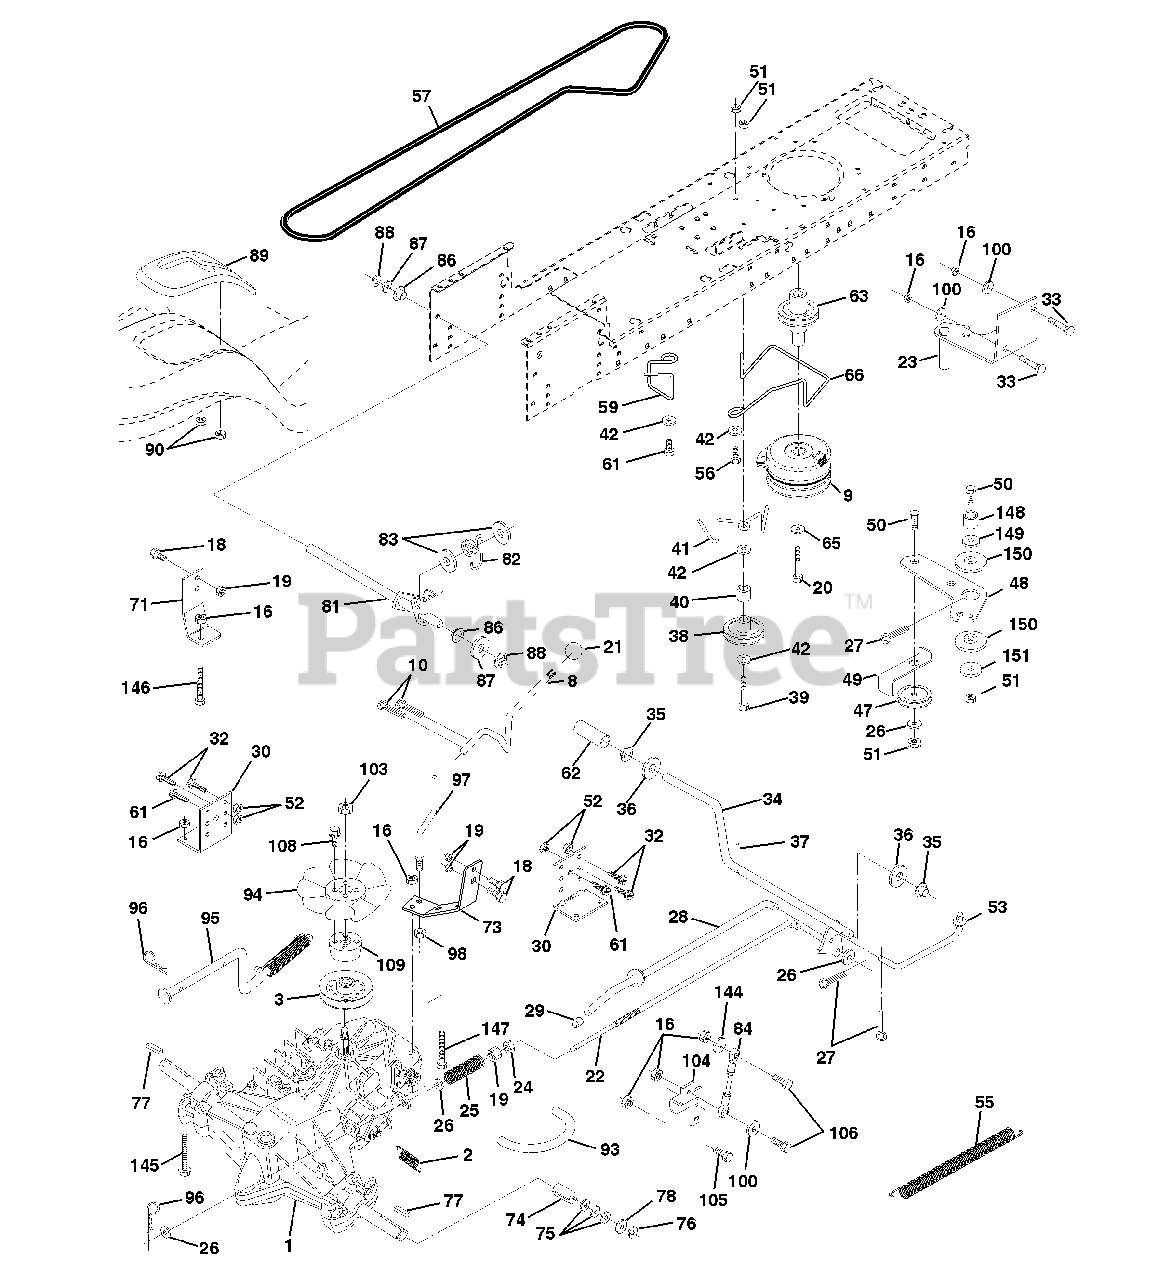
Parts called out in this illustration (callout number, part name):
1	Transaxle
2	Spring, Return, Brake
3	Pulley, Transaxle
8	Rod Shift Fender STLT
9	Clutch, Elect. EVX LT Mag 5217-2
10	Pin Cotter 1/8 x 1 CAD
16	Nut Lock Hex W/Ins. 5/16-18 Unc P
18	Bolt Fin Hex 3/8-16 Unc x 1 Gr. 5
19	Nut Lock Hex W/Wsh 3/8-16 Unc
20	Bolt Hex 7/16-20 x 4-1/4 Ga. 1.38
21	Knob, Duckhead 1/2-13
22	Rod, Brake Hydro
23	Bracket, Asm Clutch Mtg EVX
24	Nut
25	Spring, Brake Rod
26	Washer
27	Pin Cotter 1/8 x 3/4 CAD.
28	Rod, Parking Brake
29	Cap, Parking Brake
30	Bracket, Transaxle
32	Bolt Hex Hd 5/16-18 Unc x 3/4
33	Bolt Rdhd Sqnk 5/16-18 UNC x 3/4
34	Shaft, Foot Pedal
35	Bearing, Nylon
37	Pin, Roll
38	Pulley, Idler, Flat
40	Spacer, Split
41	Keeper, Belt Idler
42	Washer 13/32 x 13/16 x 12 Gauge
47	Pulley, Idler, V-Groove
48	Bellcrank Clutch Grnd Drv STL
49	Retainer, Belt
50	Bolt
52	Nut Crownlock 5/16-18
53	Link, Clutch
55	Spring, Return, Clutch
56	Bolt Fin Hex 3/8-16 UNC x 1-1/4
57	V-Belt, Ground Drive
59	Keeper, Center Span
61	Screw Thdrol. 3/8-16 x 3/4 Ty. TT
62	Cover, Pedal
63	Pulley, Clutch Electric EVX
65	Washer
66	Keeper Belt Engine Hydro
71	Strap Torque Lh Hydro
73	Strap Torque Rh Hydro
74	Spacer, Split
75	Washer 25/32 x 1-1/4 x 16 Gauge
77	Key, Square
78	Washer 25/32 x 1-5/8 x 16 Gauge
81	Shaft Asm. Cross Hydro
82	Spring Torsion T/A
83	Washer 17/32 x 3/4 x 16 Ga.
84	Rod, Tie Hydro
87	Washer 21/32 x 1-1/4 x 16 Ga.
88	Ring Klip #5304-62
89	Console, Shift
90	Nut, Self-Thd Wsh-hd 1/4 Zinc
93	Line Fuel Hydro 4"
94	Fan, Hydro 7"
95	Control Asm Bypass Hydro
96	Retainer Spring 1" Zinc/Cad
97	Keeper Belt Rh Hydro
98	Nut Keps Hex 3/8-16 Unc
100	Washer 11/32 x 3/4 x 16 Ga.
103	Nut Nylon Insert 1/2-20 Unf.
104	Arm, Control Hydro
105	Screw Cap Hex 5/16 x 18 x 1
106	Bolt Fin Hex 5/16-18 Unc x 1-1/4
108	Screw Hex Wh Hd #10-24 x
109	Adaptor Fan Hydro LT Hyd Alum
144	Washer 11/32 x 5/8 x 16 Ga
145	Bolt Hex Flghd 5/16-189 x Gr. 5
146	Bolt Hex Flghd 5/16-18 x 2-1/4
147	Bolt Hex Hghd 5/16-18 x 1/1/2
149	Spacer Retainer Pm Mower
150	Bushing Nylon Collered
151	Washer 11/32 x 2 x 10 Ga.
